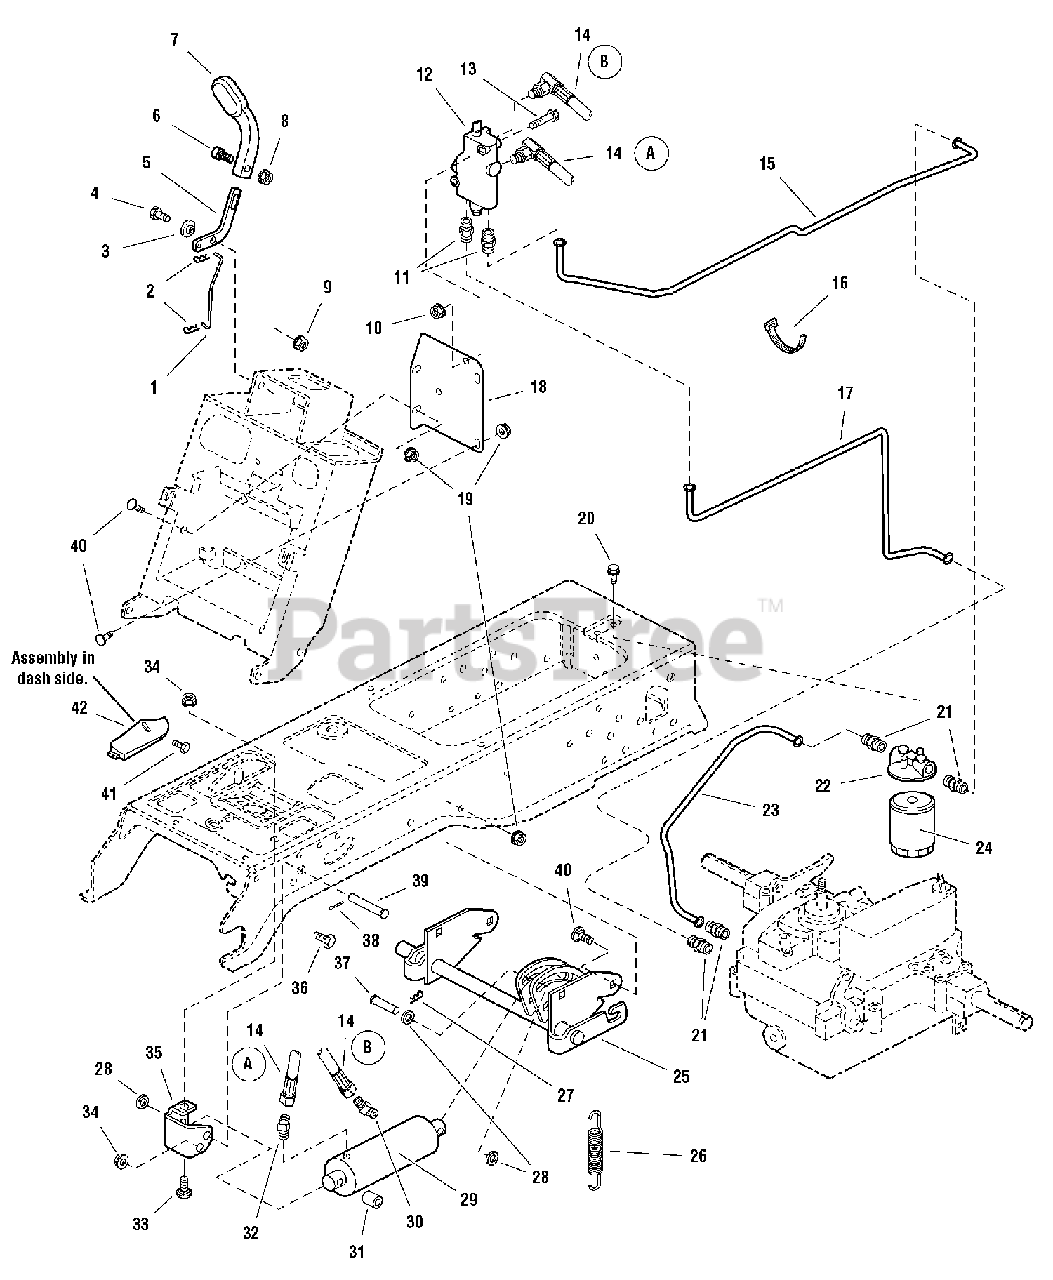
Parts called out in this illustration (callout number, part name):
1	ROD, Hydraulic Link
2	PIN, Cotter
3	SPACER, Hydraulic Lift Pivot
4	CAPSCREW, Hex Head, 5/16-18 x 3/4
5	LEVER, Hydraulic Lift
6	SCREW, Torx Plus Socket Head 1/4-20 x 7/8
7	HANDLE, Lift, Black
8	NUT, Hex Lock, ESNA Light, 1/4-20
9	NUT, Hex Lock, ESNA Light, 5/16-18
10	NUT, Hex KEPS, 1/4-20
11	FITTING, Straight 11/16-16, 3/4-16
12	VALVE, Control, 1 Spool
13	CAPSCREW, Hex Head 1/4-20 x 2
14	HOSE ASSEMBLY, Hydraulic, Rubber
15	TUBE, Steel, 6 Bends
16	TIE, Self Locking
17	TUBE, Steel, 4 Bends
19	NUT, Hex KEPS, 5/16-18
20	CAPSCREW, Hex Flange Whiz Lock, 1/4-20 x 1/2
21	FITTING, Straight 9/16-18, 11/16-16
22	BASE, Oil Filter
23	TUBE, Steel, 5 Bends
24	FILTER, Oil
25	SHIFT ASSEMBLY, Lift
26	SPRING, Extension
27	CLIP, Spring Wire
28	WASHER, 1/2 x 7/8
29	CYLINDER, Extension
30	FITTING, Elbow, 9/16-18, 1/4NPT, 90 Degrees
31	SPACER, 1-1/32" Long
32	FITTING, Tube Elbow
33	CARRIAGE BOLT, 3/8-16 x 1
34	NUT, Hex KEPS, 3/8-16
35	SUPPORT, Cylinder to Frame
36	CAPSCREW, Hex Head, 3/8-16 x 1
37	PIN, Flat Head Drilled, 1/2 x 2-1/8
38	PIN, Cotter, 1/8 x 1
40	CARRIAGE BOLT, 5/16-18 x 3/4
41	SCREW, Pan Head Torque, # 8-16 x 1/2, Plastite
42	COVER, Dash ABS (SEE NARRATIVE)
